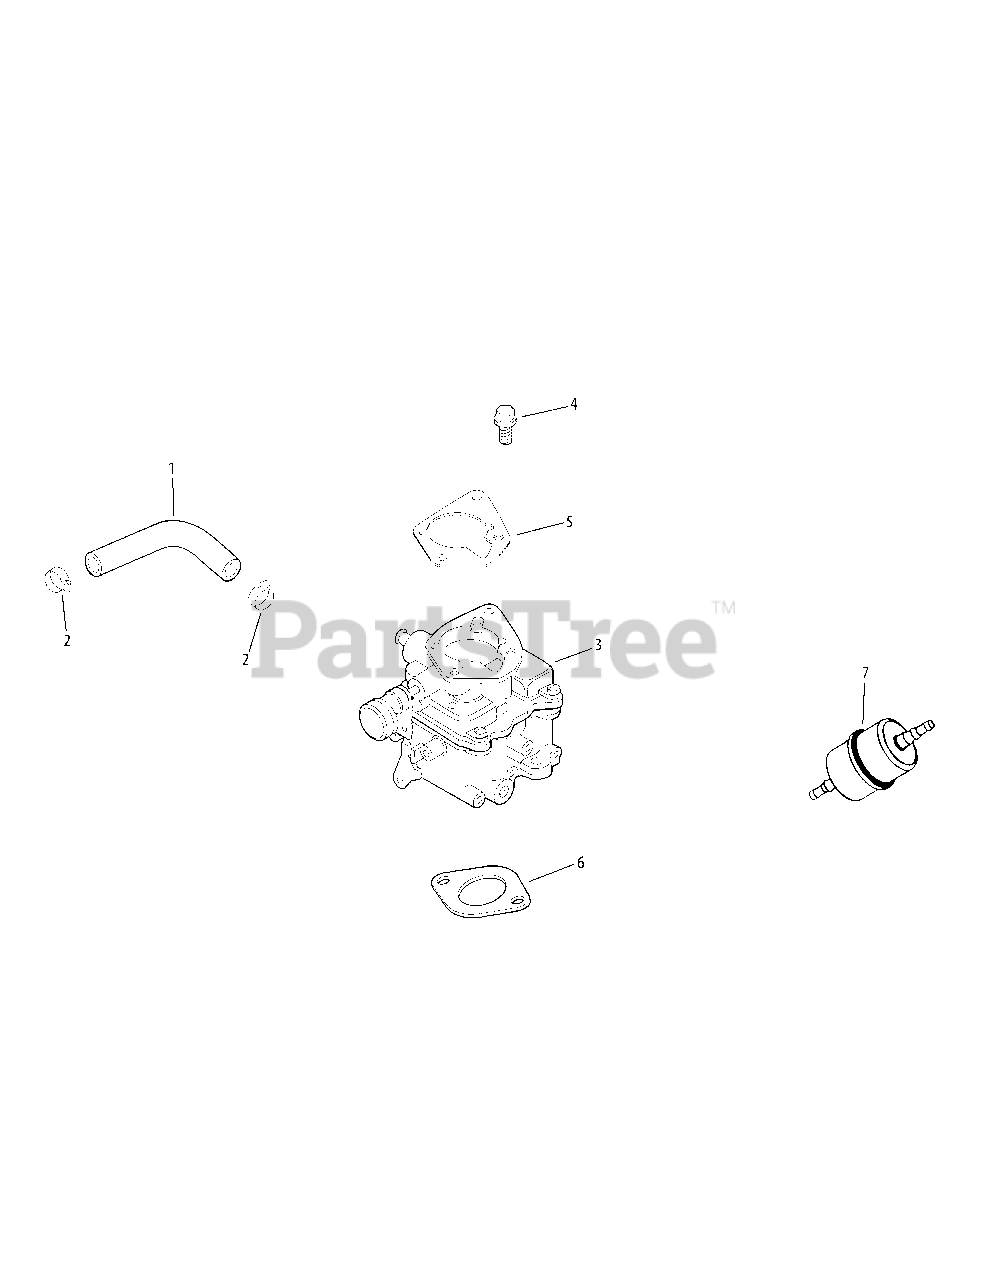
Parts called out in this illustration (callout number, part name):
1	Low Permeation Fuel Hose, 24"
2	Hose Clamp (KM)
3	Carburetor Kit w/ Gaskets
4	Flange Screw, M6 x 1.0 x 25
5	Air Cleaner Base Gasket
6	Carburetor Gasket
7	Fuel Filter
